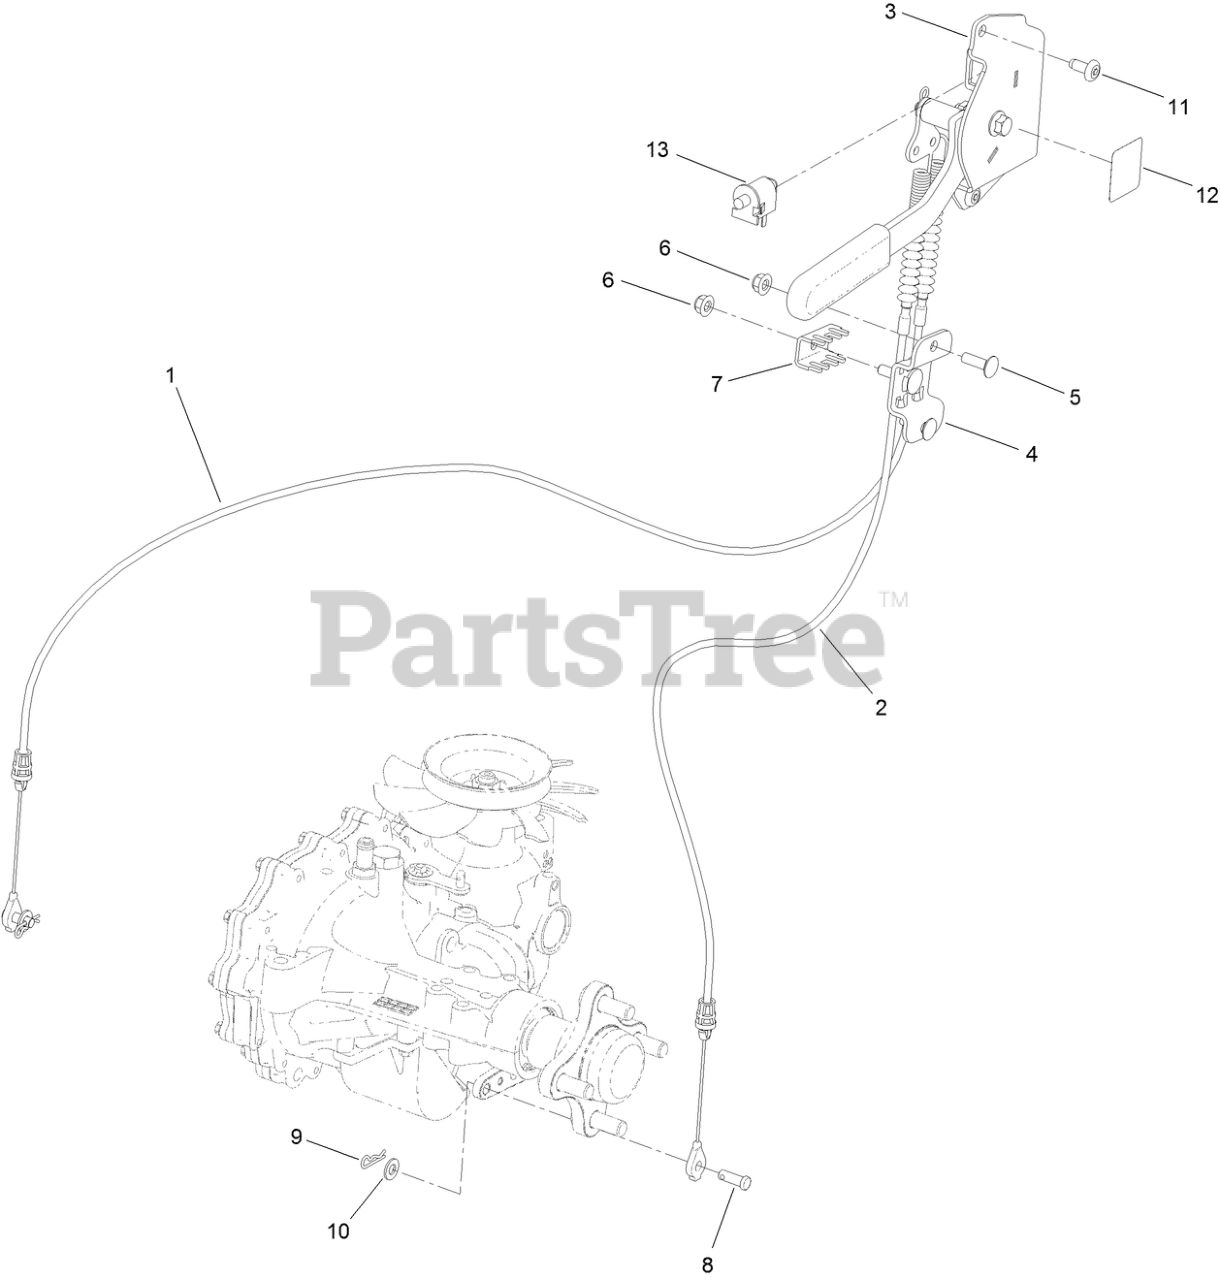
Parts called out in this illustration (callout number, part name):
1	CABLE-BRAKE
2	CABLE-BRAKE
3	BRAKE ASSEMBLY
4	MOUNT-CABLE, BRAKE
5	SCREW-CARR
6	NUT-HF, NI
7	CLAMP-CABLE
8	PIN-CLEVIS
9	PIN-COTTER
10	WASHER-PLAIN
12	DECAL-PARK BRAKE, CE
13	SWITCH-BAIL
